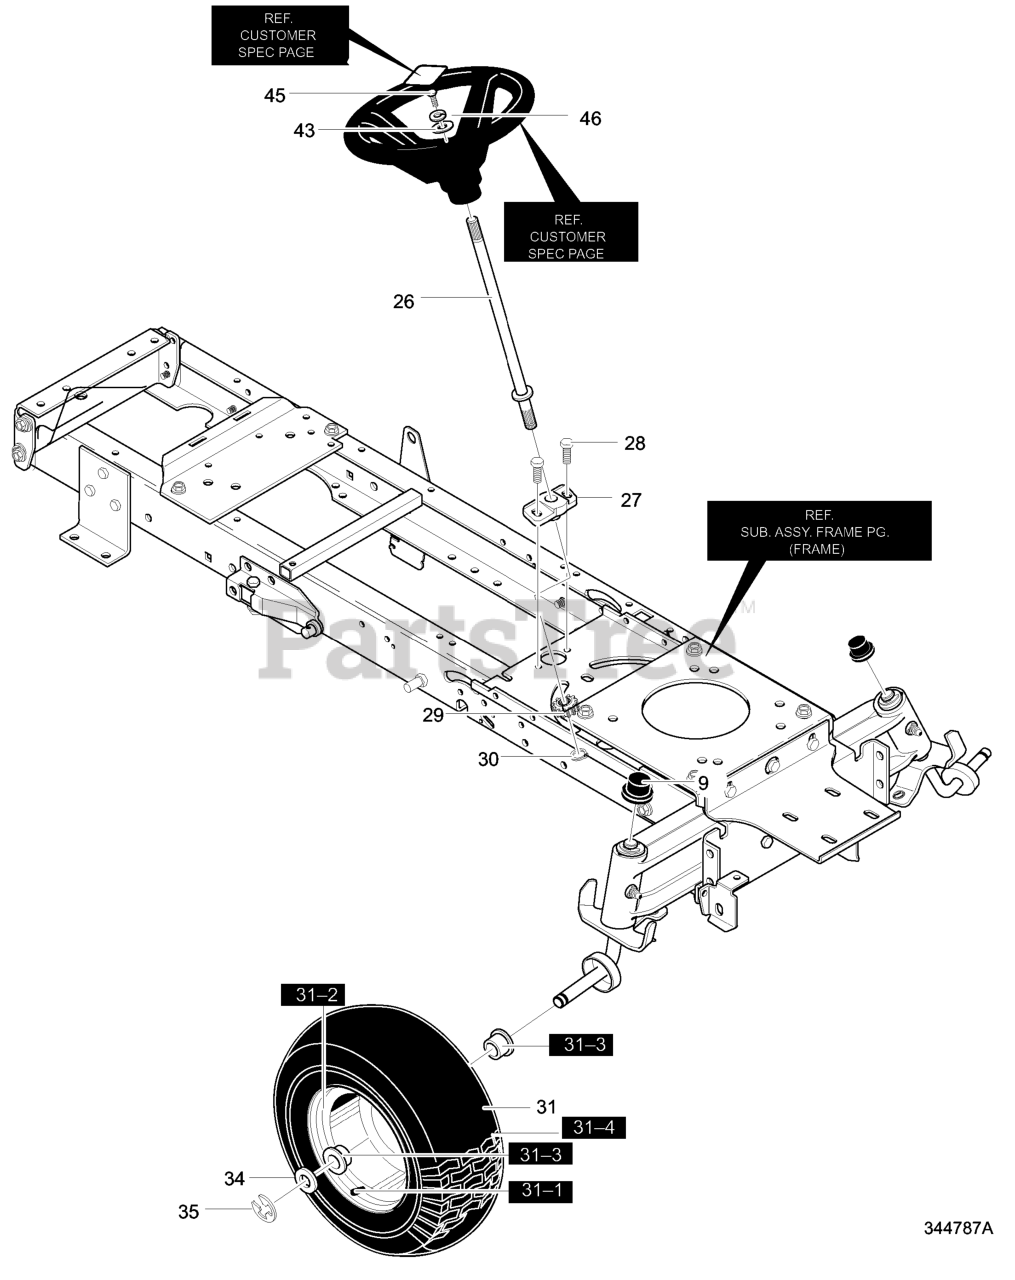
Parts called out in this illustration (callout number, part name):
9	HUB CAP
26	SHAFT, STEERING BOLT-ON
27	BEARING-LOWER
29	GEAR PINNION
30	RING, RETAINER
31	TIRE & RIM
31-1	VALVE STEM
31-3	BEARING
34	WASHER, FLAT
43	WASHER, FLAT
45	SCREW, 1/4-20X .75
46	WASHER, (18X32)
